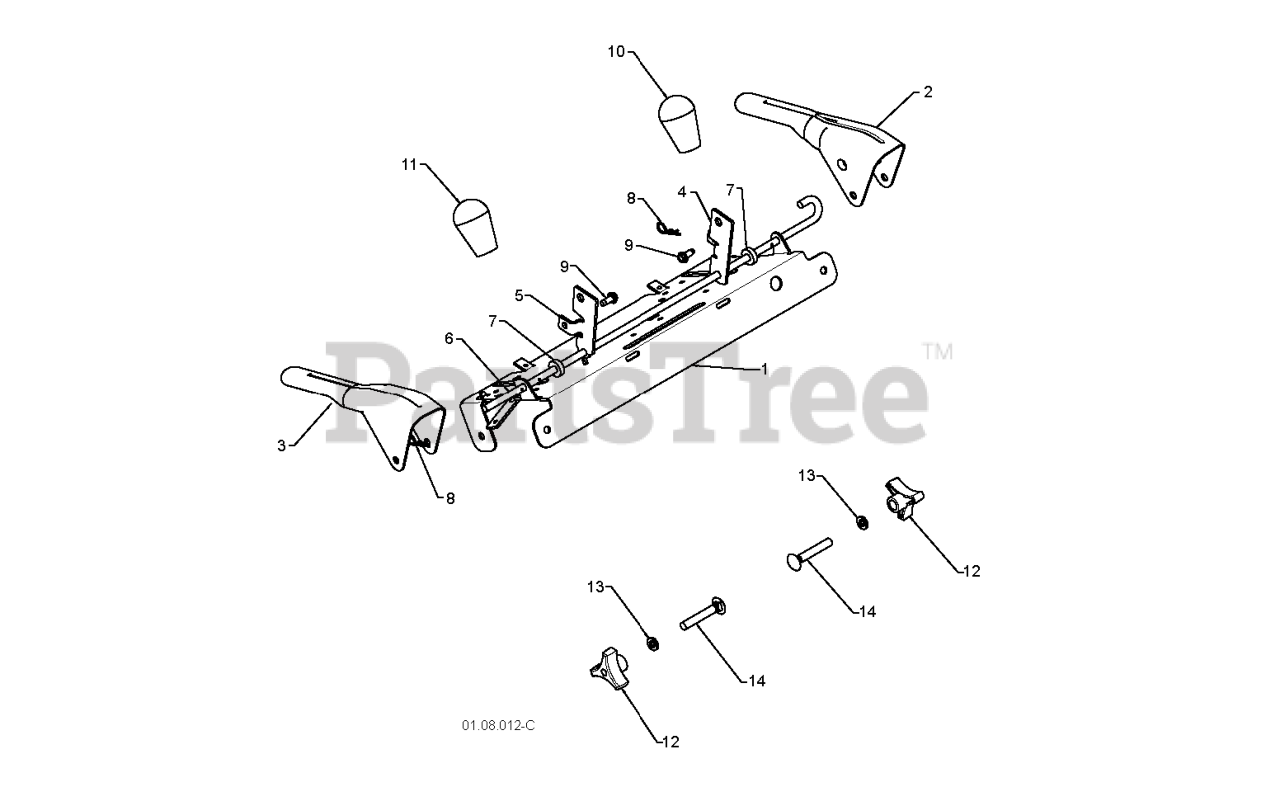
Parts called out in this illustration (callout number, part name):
1	PANEL.CONTROL
2	LEVER.CONTROL.LH.BLACK
3	LEVER.CONTROL.RH.GREY
4	ARM.TRACTION.ROD.YZ
5	ARM.IMPELLER.ROD.SNOW
6	BAIL.CONTROL.INTERLOCK
7	SPACER.CONTROL.LEVER
8	SPRING RETAINER
9	SCREW 14-20 X 5/8
10	KNOB LEVER, BLACK
11	RED KNOB SHIFTER
12	KNOB.HANDLE.3/8.TRI-POINT.BLAC
13	WASHER
14	BOLT 3/8-16 X 2-1/4
